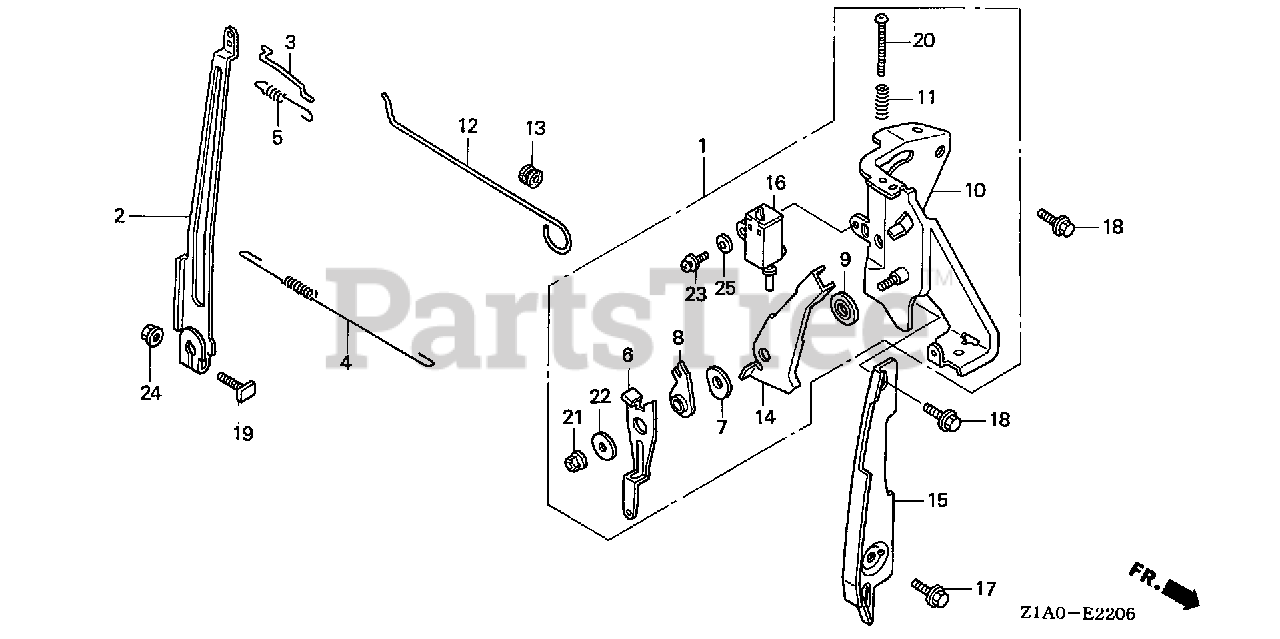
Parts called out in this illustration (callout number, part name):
1	CONTROL ASSY.
2	ARM, GOVERNOR
3	ROD, GOVERNOR
4	SPRING, GOVERNOR
5	SPRING, THROTTLE RETURN
6	LEVER, CONTROL
7	SPRING, LEVER
8	WASHER, CONTROL LEVER
9	SPACER, CONTROL LEVER
10	BASE, CONTROL
11	SPRING, CONTROL ADJUSTING Use from Engine SN 2327377.
12	ROD, CHOKE CONTROL
13	GROMMET, CHOKE ROD
14	LEVER, STOP
15	PLATE, SIDE
16	SWITCH ASSY., ENGINE STOP (N.O)
17	BOLT, FLANGE (6X12) (CT200)
18	BOLT, FLANGE (6X14)
19	BOLT, GOVERNOR ARM
20	SCREW, ADJUST
21	NUT, SELF-LOCK (6MM)
22	WASHER, WHEEL (6MM)
23	SCREW-WASHER (4X12)
24	NUT, FLANGE (6MM)
25	WASHER, PLAIN (4MM)
